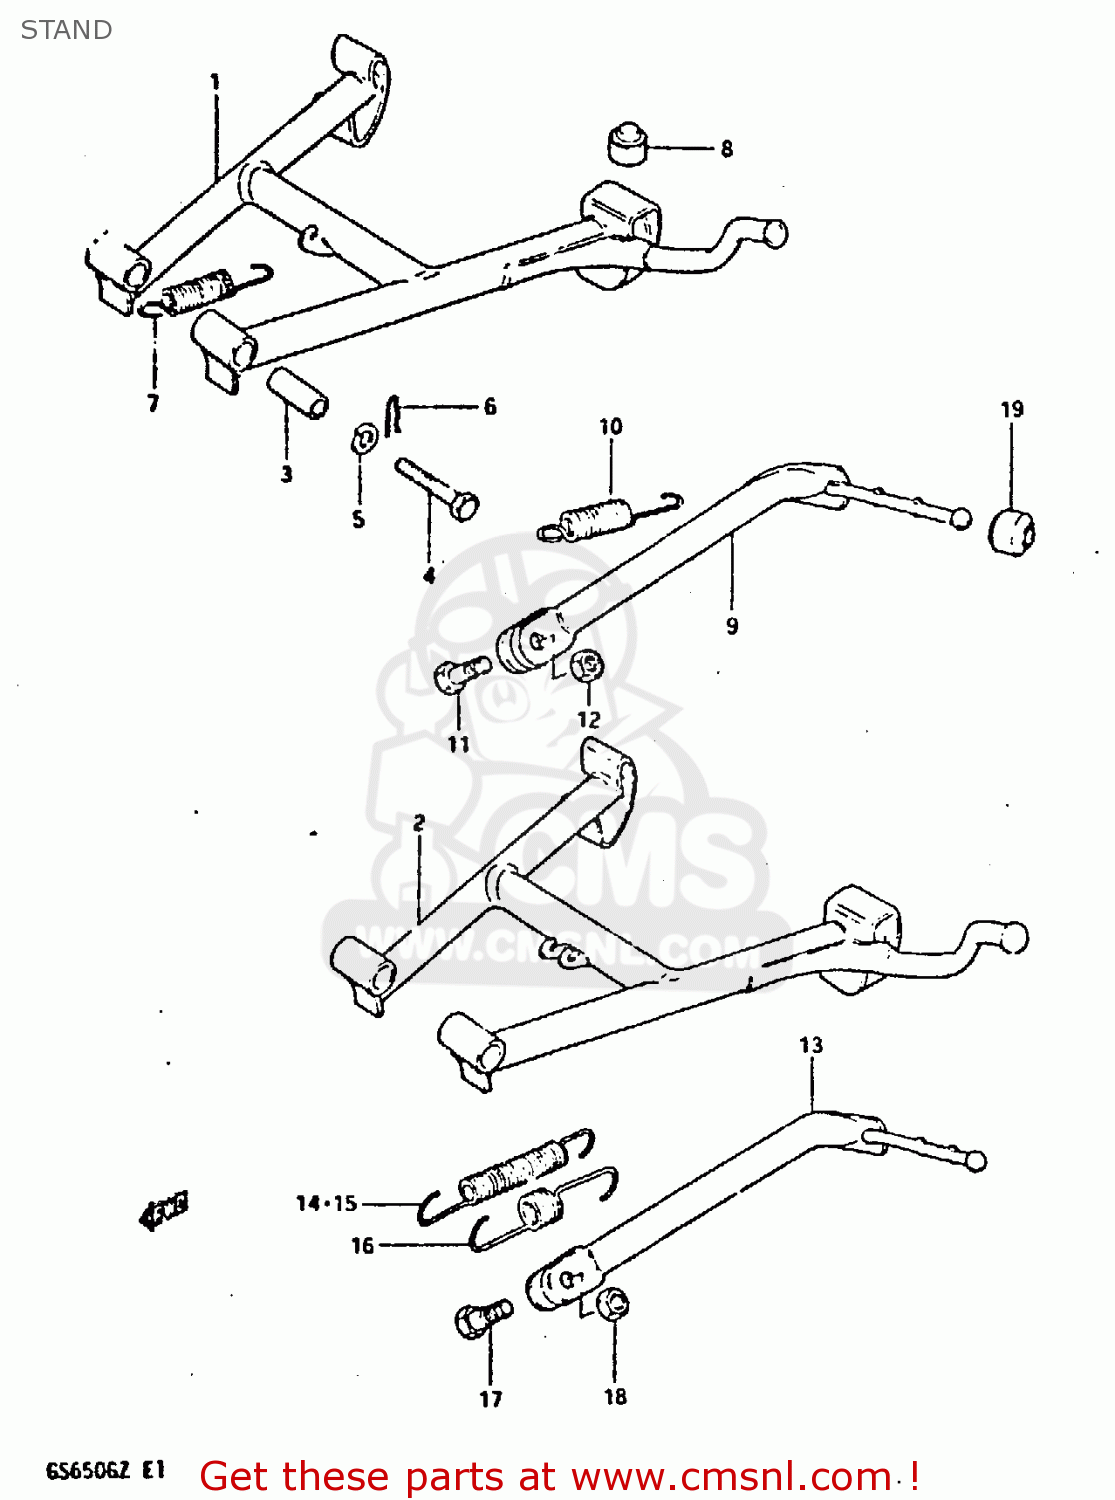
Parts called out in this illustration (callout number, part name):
1	STAND,CENTER
3	SPACER(10X16X38.8)
4	BOLT
5	LOCK WASHER
6	CLIP
7	SPRING
8	CUSHION
9	STAND,SIDE
10	SPRING
11	BOLT(10X30)
12	NUT
19	CUSHION
